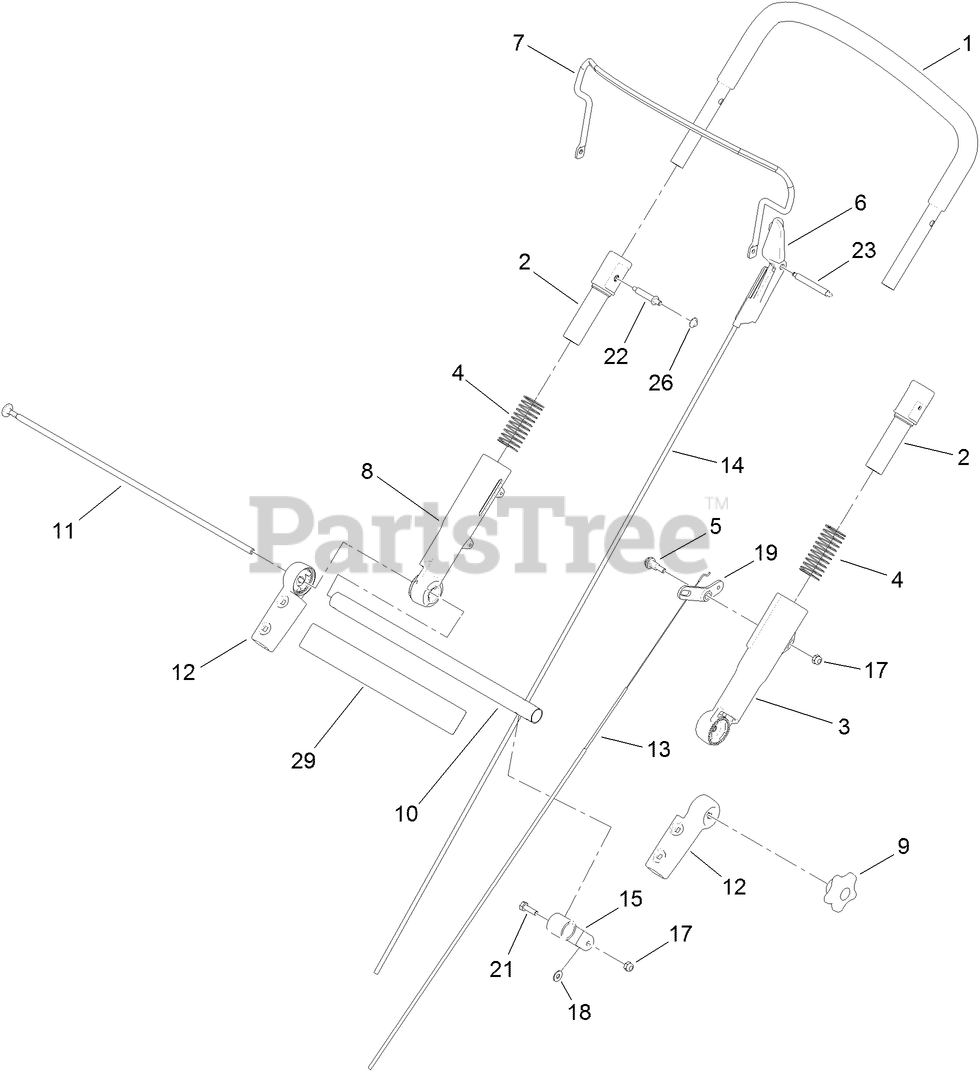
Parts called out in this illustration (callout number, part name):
1	UPPER HANDLE ASM
2	SLEEVE-INNER
3	SLEEVE-OUTER, LH
4	SPRING-COMPRESSION
5	BOLT-SHOULDER
6	STOP-PIVOT
7	BAIL-BRAKE
8	SLEEVE-OUTER, RH
9	KNOB-HANDLE
10	TUBE-CROSS
11	ROD-THREADED
12	MOUNT-HANDLE, LOWER
13	CABLE-TRACTION
14	CABLE-BRAKE
15	CLAMP-CABLE
17	NUT-LOCK, NI
18	WASHER-FLAT
19	LEVER-TRACTION
21	SCREW-HH
22	PIN-HANDLE
23	PIN-BAIL, LH
26	RETAINER-PUSH ON
29	DECAL-ADS
